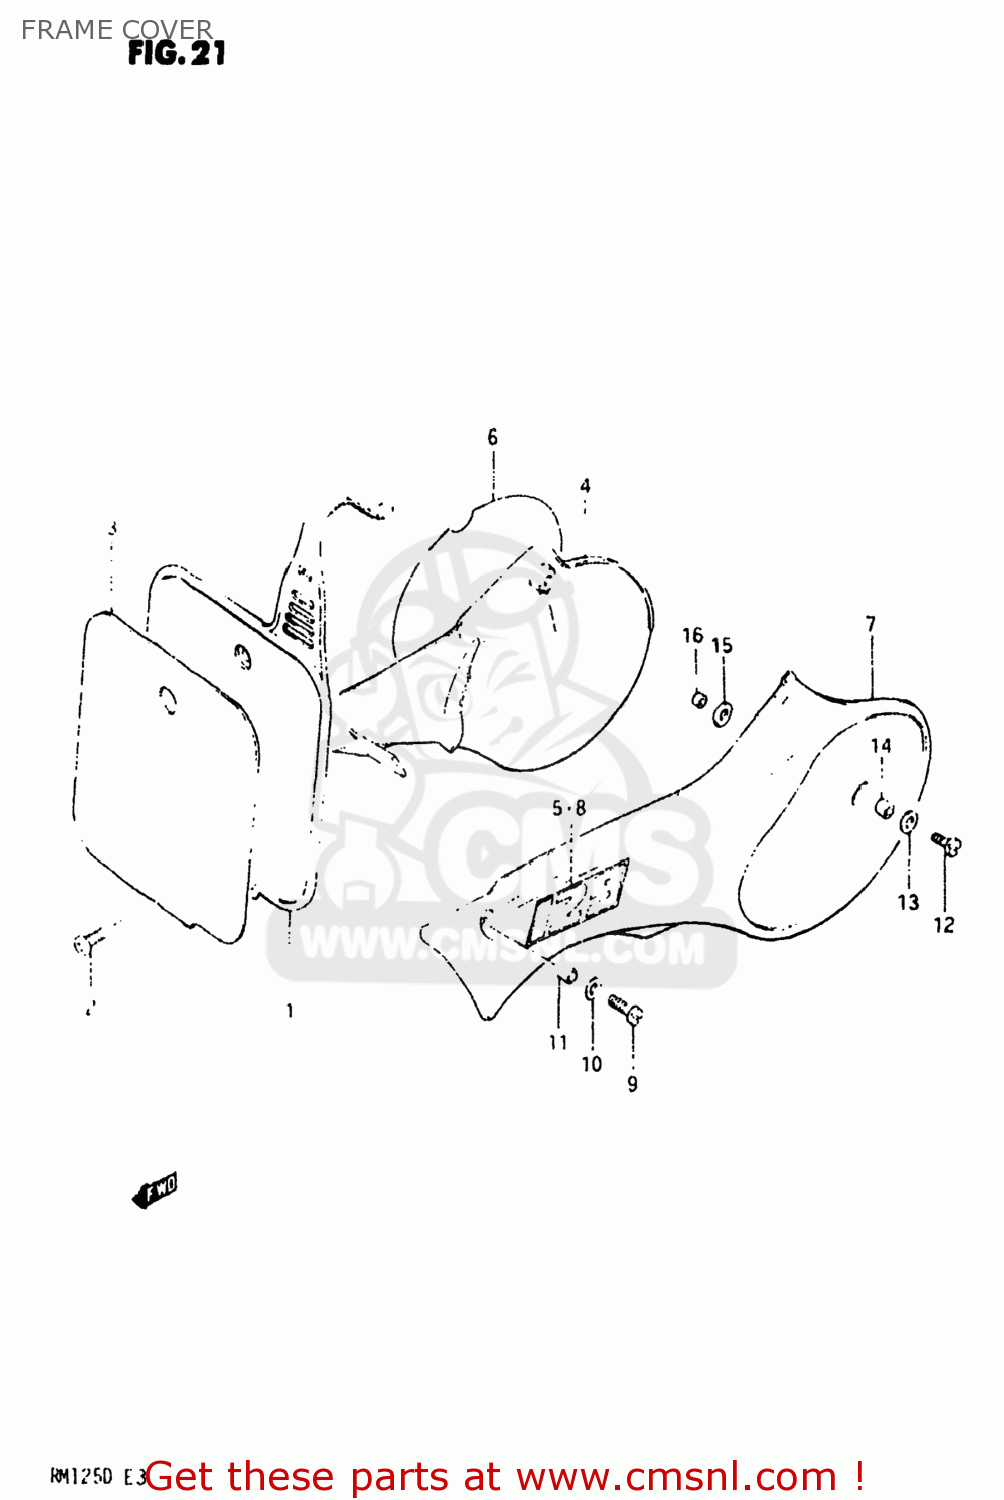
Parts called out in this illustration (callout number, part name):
1	PLATE,NUMBER,FRONT
2	SCREW
3	EMBLEM,FRONT NUMBER PLATE
4	COVER,FRAME,R(YELLOW)
5	EMBLEM,FRAME COVER,RIGHT
6	EMBLEM,FRAME COVER NUMBER
7	COVER,FRAME,LEFT
8	EMBLEM,FRAME COVER,LEFT
9	SCREW(6X14)
10	WASHER, REAR
11	SPACER (6.1X8X3.5)
12	SCREW(6X14)
13	WASHER, REAR
14	SPACER
15	GASKET
16	SPACER (6.1X8X3.5)
